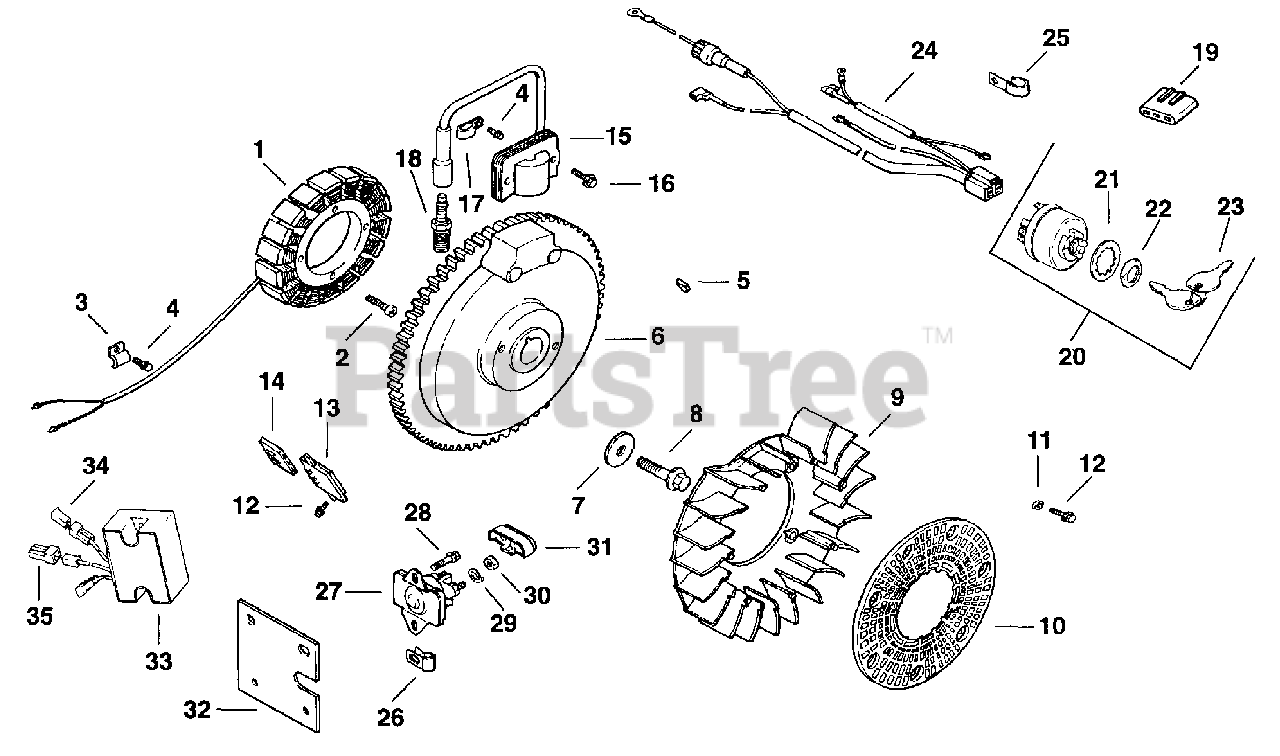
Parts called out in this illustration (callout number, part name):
2	SCREW, WSH HD TAP #10-32x9/16" USE 25 086 110-S
4	SCREW - USE M-545010
5	KEY, 3/16" X 5/8"
6	FLYWHEEL - USE 12 025 29
7	WASHER, FLAT 13/32"
8	SCREW, FLG M10X1.5X60 - DISC.
9	FAN - USE 12 157 03
10	SCREEN, GRASS
11	BOLT - USE 25 086 47
12	SCREW - USE M-639016
15	MODULE - USE 12 584 05
16	Screw, hex. flange M5x0.8x20
18	PLUG, SPARK (STD)
